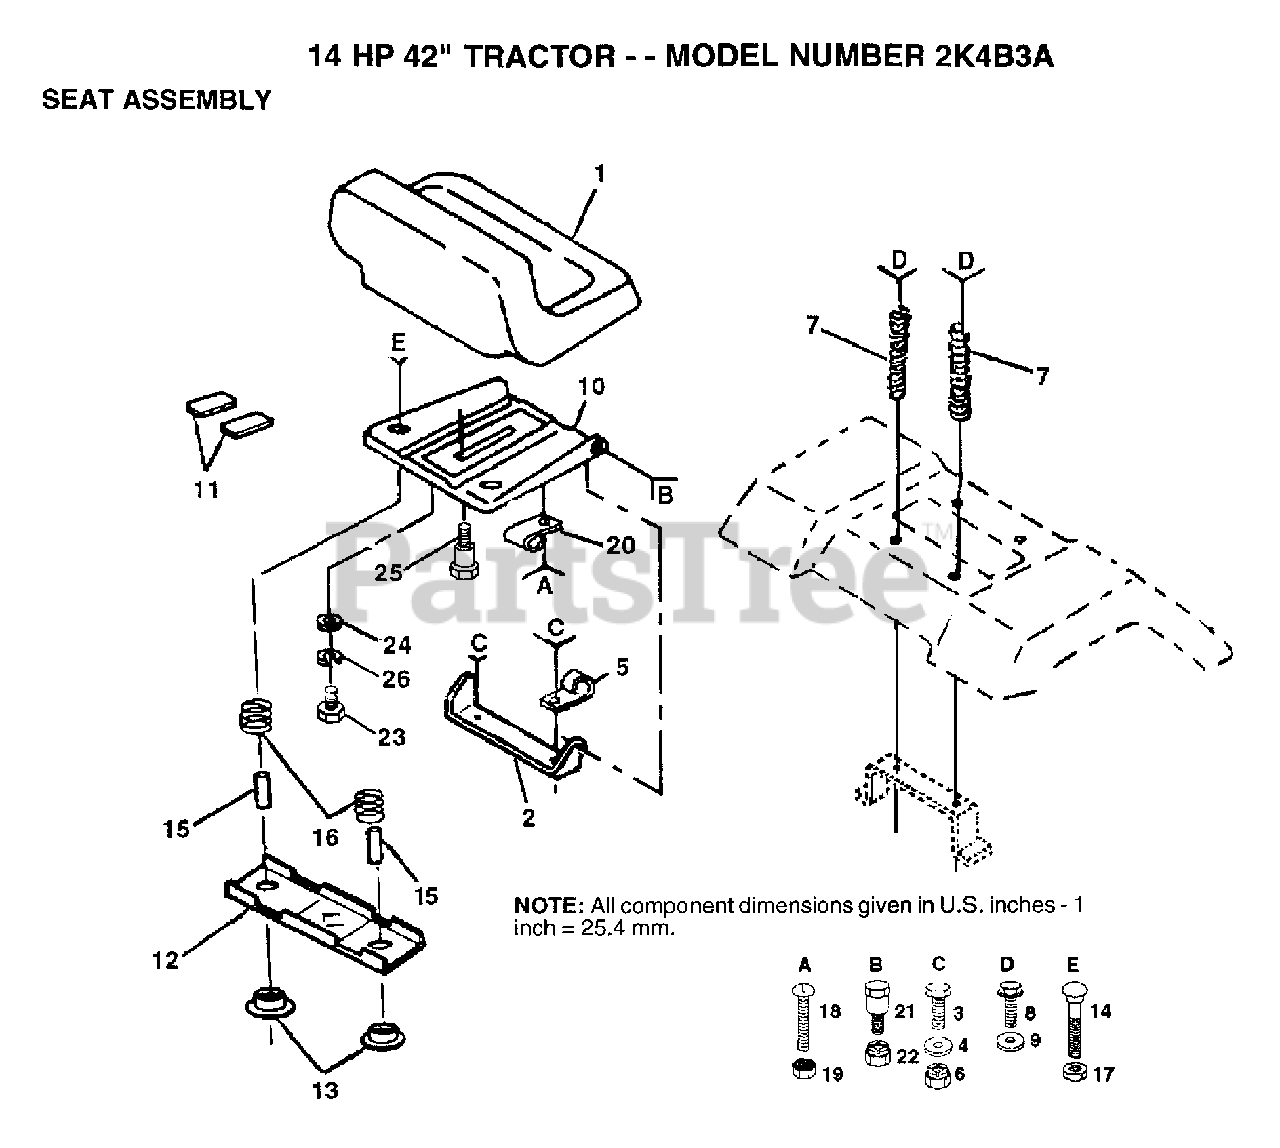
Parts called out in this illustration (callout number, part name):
4	WASHER
5	CLIP T
7	SPRING COMPRESSIO
8	SCREW GTV
9	WASHER
11	STRIP FORM
12	BRKT SWITCH
13	BUSHING
14	BOLT, CARRIAGE
15	SPLIT SPACER
16	SPRING
19	"NUT,KEPS"
23	BOLT
24	WASHER
25	"BOLT,SHOULDER"
26	LOCKWASHER
